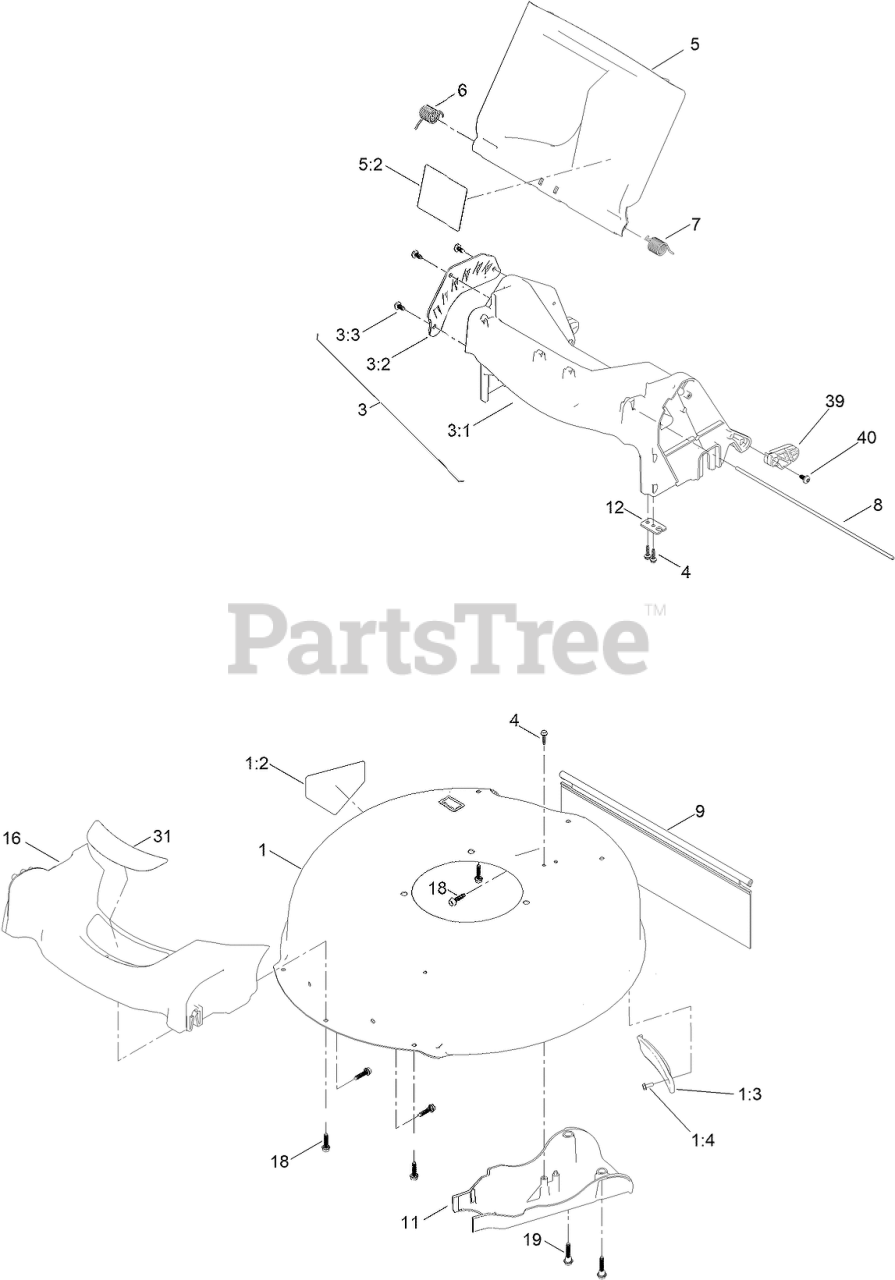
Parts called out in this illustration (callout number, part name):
1	HOUSING ASM
1:2	DECAL-DANGER
1:3	COVER-BELT
1:4	SCREW-TAPTITE
3	CHUTE ASM
3:1	CHUTE-SP/AWD, 21 IN
3:2	PLATE-HOC
3:3	SCREW-PLASTIC,PH
4	SCREW-HWH
5	REAR DEFLECTOR ASM (60V)
5:2	DECAL-WPM WARNING, 60V
6	SPRING-TORSION
7	SPRING-TORSION
8	ROD-DOOR
9	SHIELD-TRAILING
11	COVER-BELT
12	BRACKET-CABLE
16	BUMPER
18	SCREW-FLANGE, PLASTIC
19	SCREW-SHOULDER, HHF
31	DECAL-DECK
39	PAD-STOW, SMART
40	SCREW-PLASTIC,PH
